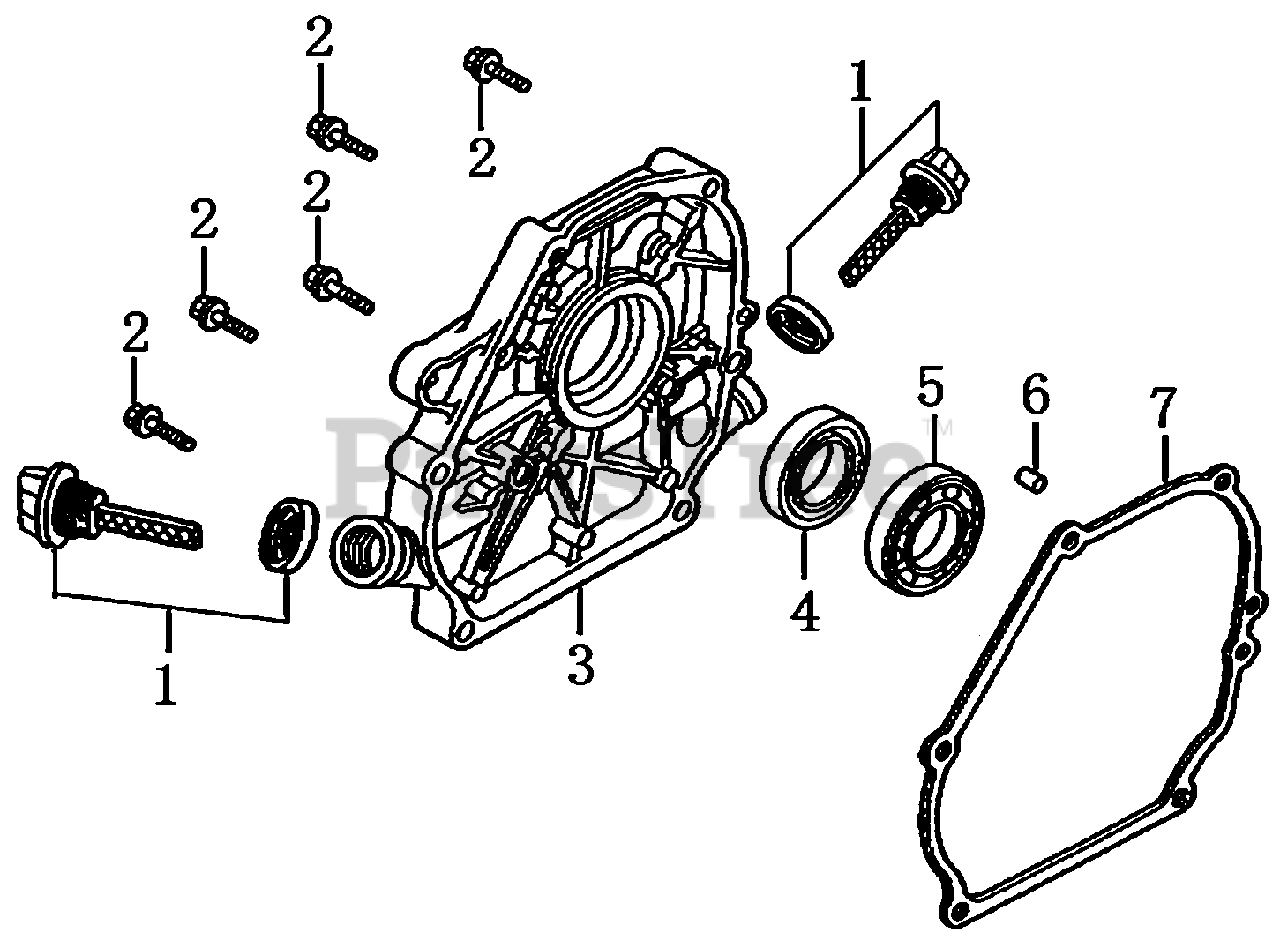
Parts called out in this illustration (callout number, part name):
1	CAP ASSY. DIP STICK
2	BOLT, FLANGE
3	CASE COVER
4	OIL SEAL 25x41.25x6
5	BEARING, RADIAL BALL
6	PIN, DOWEL
7	GASKET, CASE COVER
